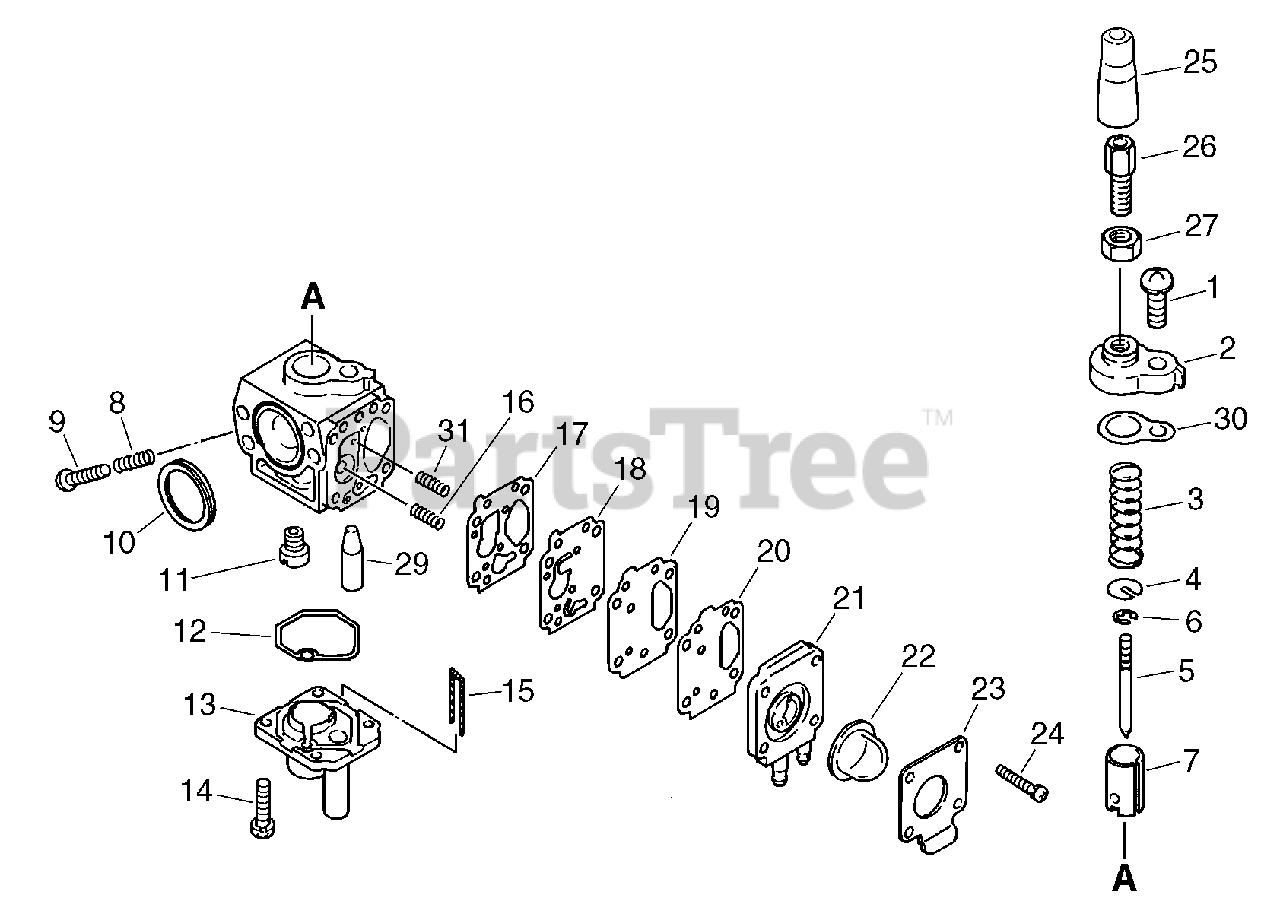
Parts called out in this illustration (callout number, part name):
1	SCREW - 5X16
2	COVER - TOP
3	SPRING, THROTTLE
4	SEAT, SPRING
5	NEEDLE, JET
6	RING, RETAINING
7	VALVE, THROTTLE
9	SCREW, IDLE ADJUST
11	JET, MAIN
12	GASKET, CHAMBER
13	CHAMBER, FLOAT
14	SCREW - 3X10
15	WIRE, DRAIN
17	GASKET, PUMP
18	DIAPHRAGM, PUMP
19	PLATE, PUMP
20	GASKET, PUMP
21	COVER, PUMP
22	BULB, PURGE
23	COVER, PUMP
24	SCREW - 3X14
25	COVER, DUST
26	NUT, CABLE ADJUST
29	JET, MAIN - 64
